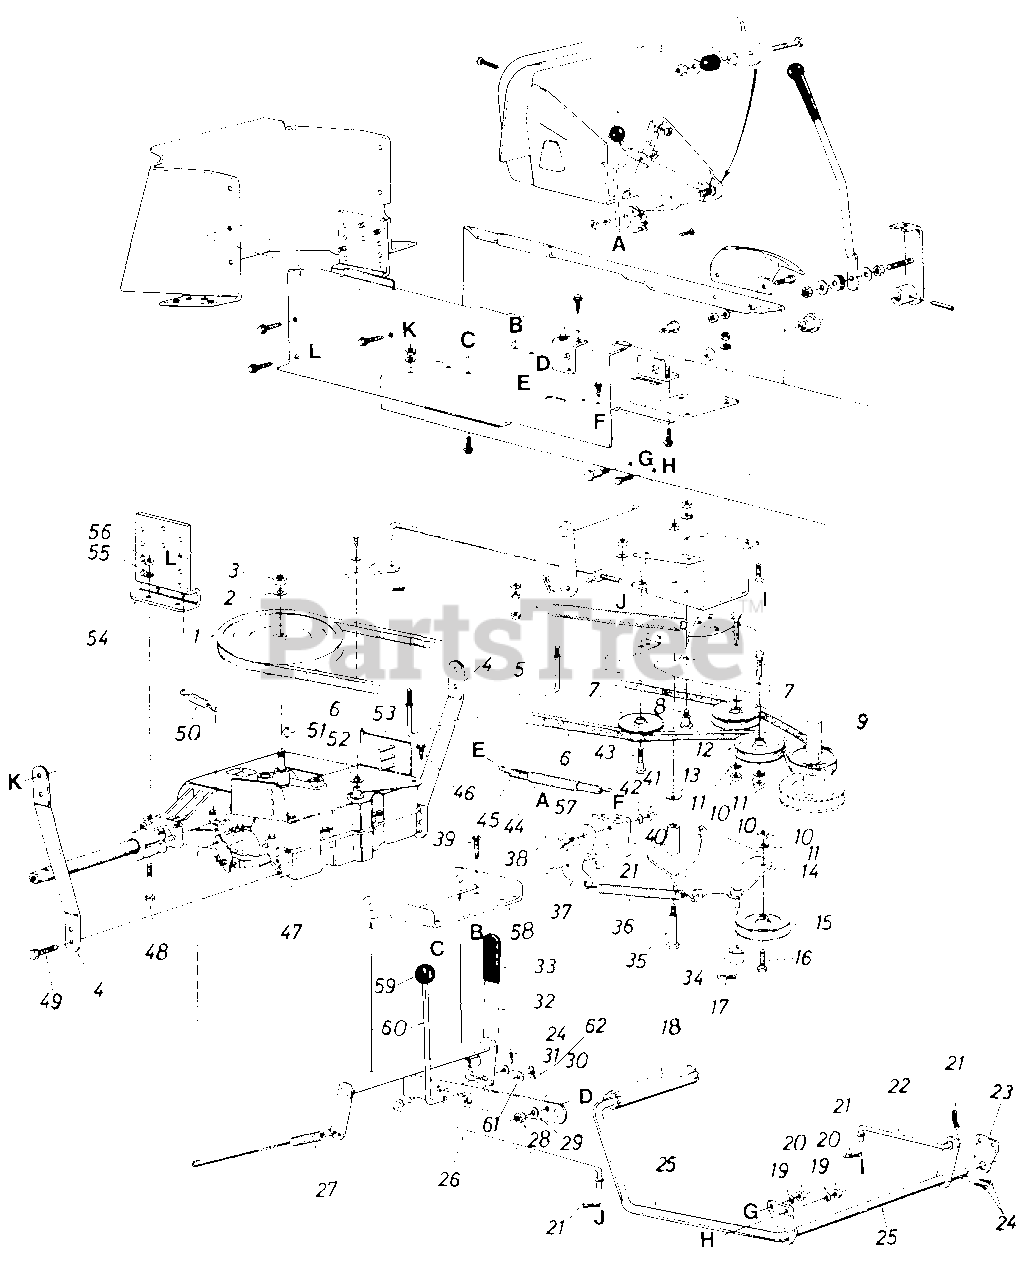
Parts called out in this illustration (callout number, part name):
1	8" "V"-Pulley
2	L-Wash. 1/2" I.D.
3	Hex Nut 1/2-20 Thd.
4	Transaxle Brace
5	Belt Guard
6	"V "-Belt 1/2" x 89" Lg. (Kevlar)
7	"V"-Belt Idler Pulley .38" I.D. x 3-1/16" O.D.
8	Shoulder Bolt .435" Dia. x .160 (5/16-18)
9	Two Step Engine Pulley 3.10" & 5.56" Dia.
10	Hex Nut 3/8-16 Thd.
11	L-Wash. 3/8" I.D.
12	Flat Idler Pulley 2.75" O.D.
13	Belleville Wash. .400" I.D. x .88" O.D. x .063
14	Idler Bracket Ass'y.
15	4" "V"-Idler Pulley
16	Hex Bolt 3/8-16 x 1.25" Lg.
17	Hairpin Cotter 5/16" Dia.
18	Foot Pad
19	L-Wash. 3/8" I.D.
20	Hex Nut 3/8-16 Thd.*
21	Hairpin Cotter 3/8" Dia.
22	Brake Clutch Rod (4.60" Lg.)
23	Clutch Rod Bearing Brkt.
24	Cotter Pin 1/8" Dia. x 1.00" Lg.*
25	Clutch Brake Pedal Ass'y.
26	Brake Cam Rod (13.60" Lg.)
27	Extension Spring .59" O.D. x.93" Lg.
28	Hex Nut 5/16-18 Thd.
29	L-Wash. 5/16" I.D.
30	Parking Brake Cam
31	Fl-Wash. .406" I.D. x 1.00" O.D. x .030 Thk.
32	Hand Brake Lever Ass'y.
33	Grip-Flat Bar 1-1/4" Wide
34	Spacer
35	Shoulder Bolt .496" Dia. x 2.00" Lg. (3/8-16)
36	Extension Spring .620" O.D. x6.12" Lg.
37	Deck Control Brkt.
38	Deck Control Rod
39	Hex Bolt 5/16-18 x 1.50" Lg.*
40	Parking Brake Cam Mtg. Brkt.
41	Hex Nut 5/16-18 Thd.*
42	L-Wash. 5/16" I.D.*
43	Hex Bolt 3/8-24 x 1.50" Lg. (Grade 5)
44	Convoluted Conduit .50" I.D. x4.0" Lg.
45	Ext. Spring .50" O.D. x 6.37" Lg.
46	Hex Wash. Hd. AB Tap Scr. 5/16-24 x .75" Lg.
47	Transaxle
48	Hex Bolt 5/16-18 x 2.50" Lg.*
49	Hex Wash. Hd. AB Tap Scr. 5/16-24 x .75" Lg.
50	Extension Spring .50" O.D. x 2.75" Lg.
51	Hi-Pro Key 3/32" x 5/8" Dia.
52	Special Wash. 1.00" O.D. (Hdn.)
53	Transaxle Belt Keeper Ass'y.
54	Transaxle Support Bracket
55	L-Wash. 5/16" I.D.*
56	Hex Nut 5/16-18 Thd.*
57	Shoulder Bolt .437" Dia. x .162" Lg. (5/16-18)
58	Idler Mtg. Brkt.
59	Ball Knob
60	Parking Brake Link
61	Fl-Wash.
62	Hairpin Cotter
